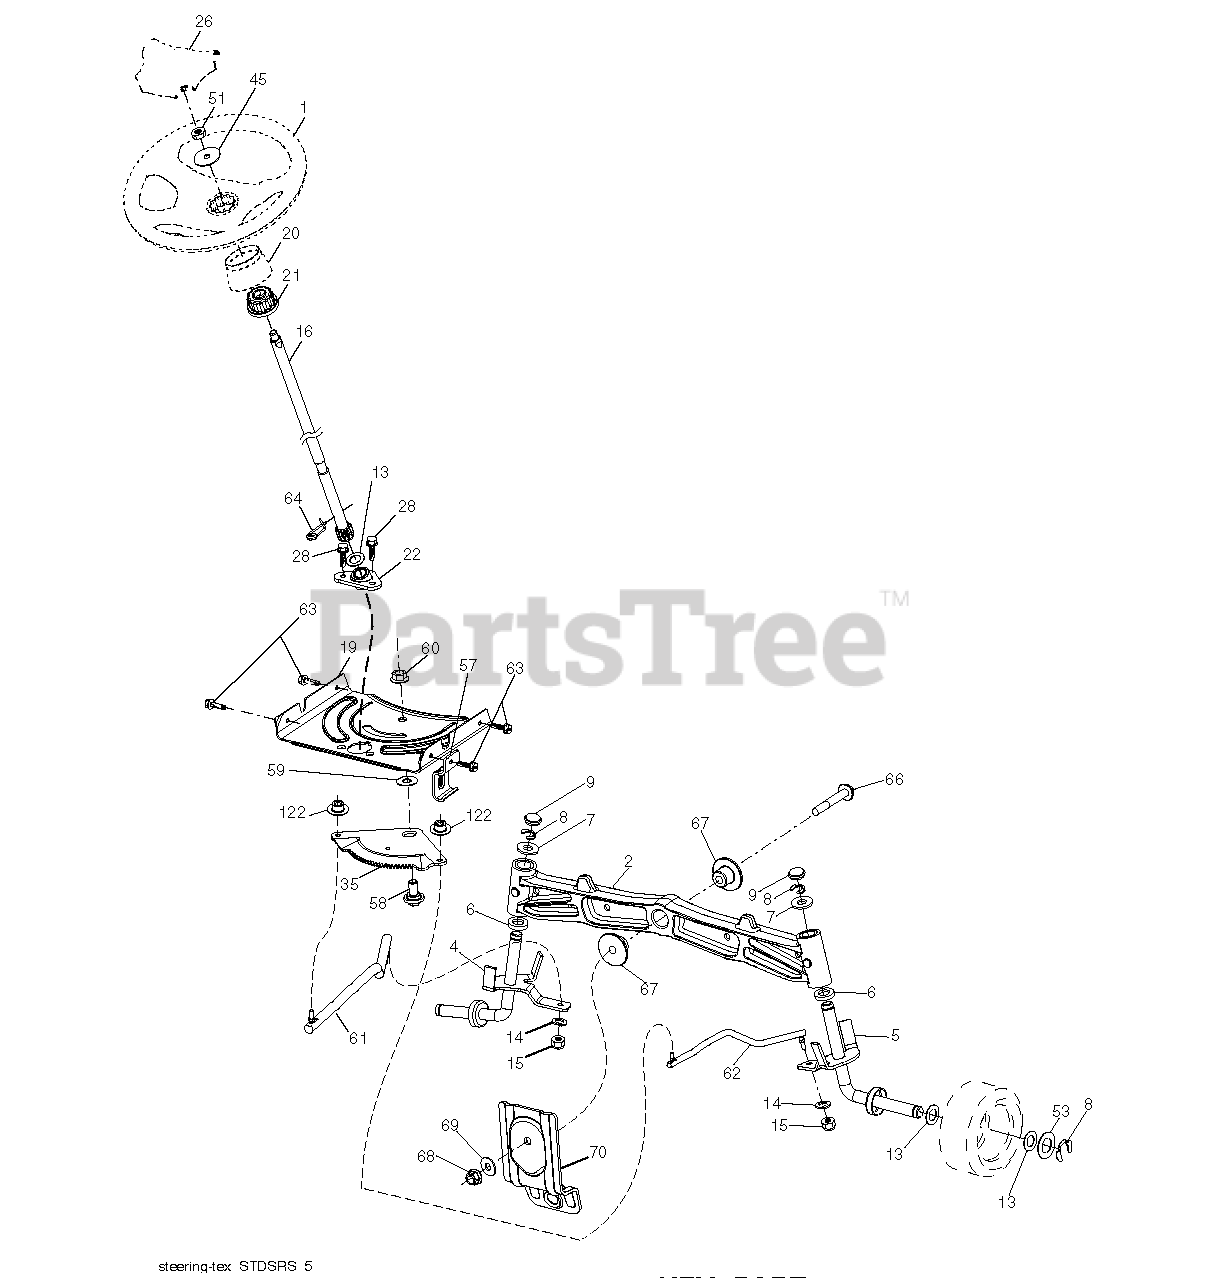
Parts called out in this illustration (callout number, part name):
1	WHEEL, STEERING
4	SPINDLE ASSY LH
5	SPINDLE.WELDED.RH.16"TEX
6	BRNG T
14	WASHER, LOCK 3/8
15	NUT CROWNLOCK 3/8-24
19	PLATE.STEER.DDL.NLT/NG
20	BOOT.STEERING.
21	ADAPTER, WHEEL STNG
22	STEERING.SUPT.LOWER.
26	INSERT, WHEEL STEERING
28	SCREW, 3/8-16X3/4
35	GEAR.SECTOR.PLATE.DDL.
57	BRKT.UPSTOP.GT/LT.TEX
58	BOLT.SHOULDER.SECTOR.P
59	WASHER.THURST.SECTOR.S
60	NUT FLANGE LOCK 5/8-11
61	DRAGLINK.LH.BALLSTUD.D
62	DRAGLINK.RH.BALLSTUD.D
63	SCREW
64	RETAINER.CLIP.SPRING.S
66	BOLT HEX FGHD 7/16-14 X 3 SERR
67	BUSHING.PM.FRONT AXLE
68	NUT.LOCK.FLANGE.7/16
69	WASHER.1.5X.505X.118
70	BRKT.DECK.SUSPENSION.F
